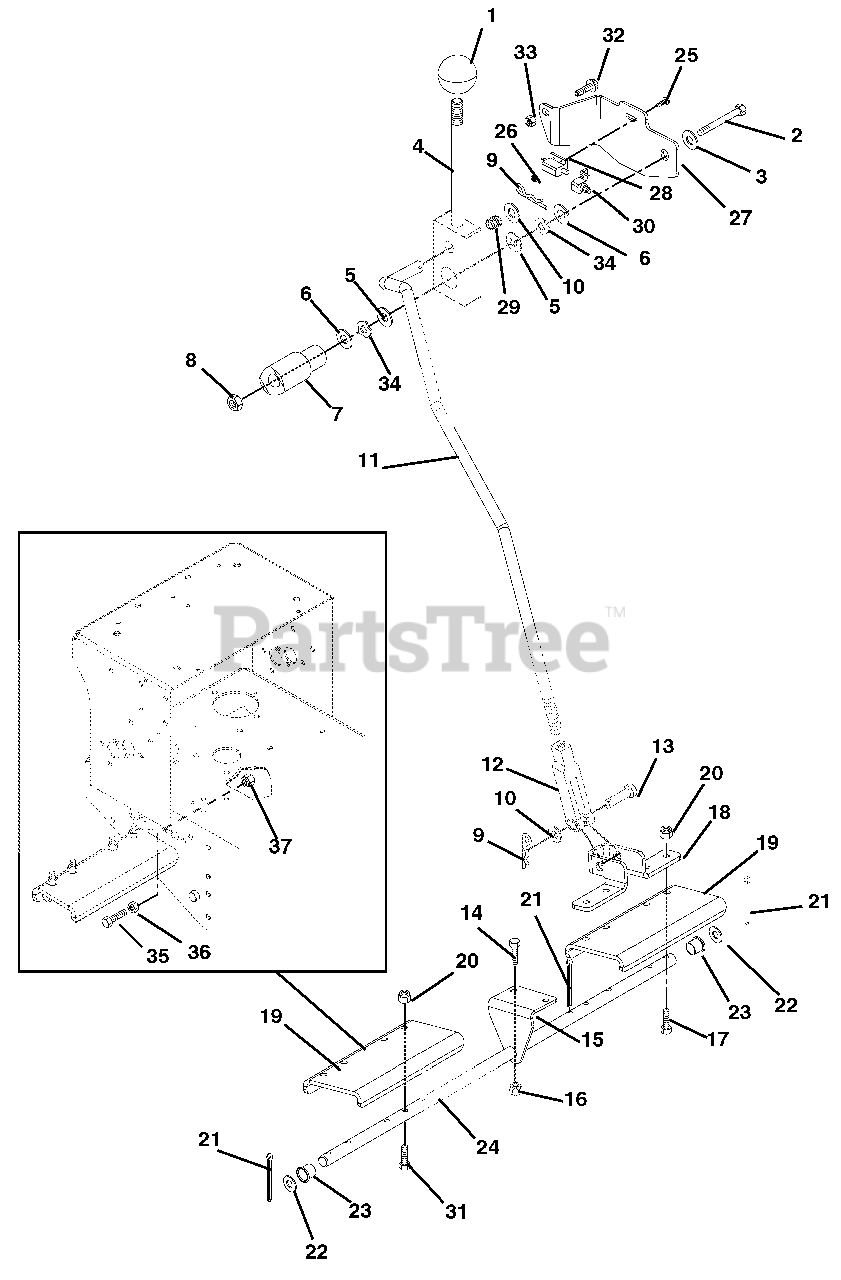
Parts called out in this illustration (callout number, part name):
1	Knob, Ball-Black 1-.41, .375-1
2	Bolt-Hex .44-14 x 4.5 Grade 5
3	Washer-Flat-Steel .50 x 1.25 x .083
4	Weldment- Handle
5	Washer-Flat-Nylon .76 x 1.25 x .030
6	Washer-Flat-Steel .76 x 1.38 x .062
7	Pivot, Brake
8	Nut-Locking-Hex .44-14
9	Pin-Hair Internal .08 x .18 x 1.18
10	Washer-Flat-Steel .406 x .812 x .065
11	Rod, Brake
12	Clevis,.38-24 Adjustable
13	Pin-Clevis .37 x 1.75
14	Bolt-Hex .38-16X1.00 Grade 5
15	Bracket, Brake Shaft
16	Nut-Locking-Nylon .38-16
17	Bolt-Hex .25-20 x 1.50 Grade 5
18	Brake, Arm
19	Pad, Brake
20	Nut-Locking-Nylon .25-20
21	Pin-Cotter .12 x 1.00
22	Washer-Flat-Steel .656 x 1.31 x .095
23	Bushing-Flange .63 x 1.00 x .625 Nylon
24	Brake, Shaft
25	Screw-Machine 10-24 x .75 Hex Washer Head
26	Nut-Locking-Nylon 10-24 with Insert
27	Bracket, Parking Brake Switch
28	Switch, Interlock
29	Spring-Compression .045 x .60 x .75
30	Boot, Rubber
31	Bolt-Hex .25-20 x 1.25 Grade 5
32	Bolt-Serrated Hex Flange Washer Head .25-20 x .75
33	Nut-Locking-Top-Flange .25-20
34	Washer-Wave .076 x 1.12 x .080
35	Bolt-Hex .38-16 x 1.75 Grade 5
36	Nut-Hex .38-16
37	Nut-Locking-Nylon .38-16
